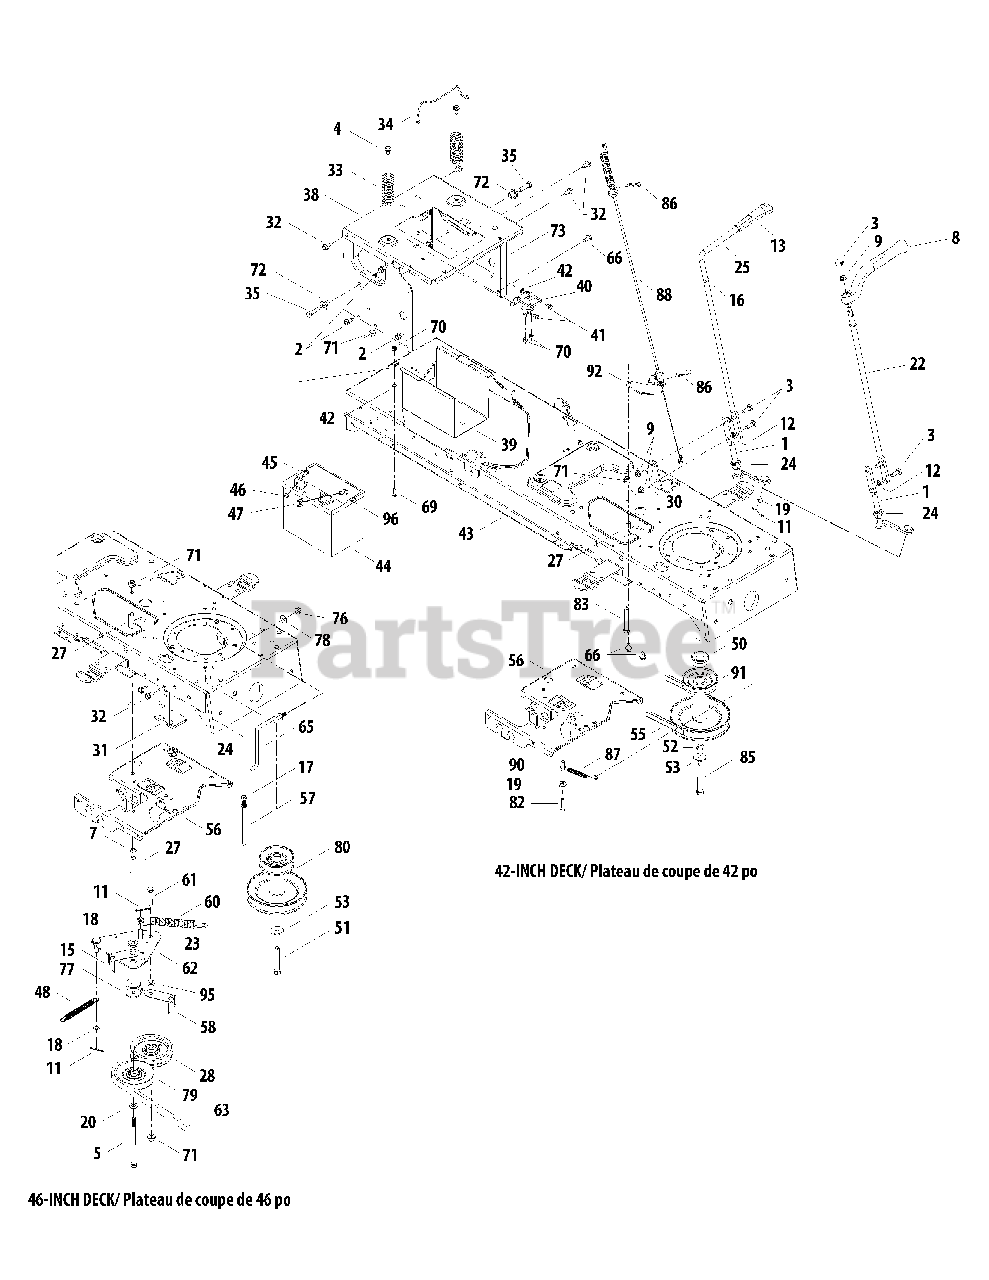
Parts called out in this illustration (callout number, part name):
1	PTO Engage Lever Assembly
2	Hex TT Scr. 5/16-18 x .75
3	Carriage Bolt 5/16-18 x 1.00" Lg
4	Hex Wash HD AB Tap Scr 5/16-12 x .75
5	Hex Cap Screw, 3/8-16 x 1.5
7	Push Nut Bolt Retainer
9	Hex Flange L-Nut 5/16-18
11	Cotter Pin 1/8" Dia x 1.00
12	Push Speed Nut
16	Flat Washer .510 ID x .75 OD x .033
17	L-Wash 5/16 ID
18	Flat Washer .385 ID x .62 OD x .06
19	Flat Washer .28 ID x .74 OD x .063
20	Flat Washer .385 ID x .87 OD x .06
21	Cap Plug .812 dia.
22	Deck Engagement Handle
23	Shoulder Spacer
24	Hex Slpit Flange Bearing .50 ID
25	Deck Engagement Handle
27	Spacer .385 ID x .635 OD x 1.54
28	Flat Idler Pulley 3.5 OD
30	Engagement Stop Bracket
31	Deck Stop
32	Hex Wash HD AB Tap Scr 5/16 x .75
33	Compression Spring 1.28 x 3.125
34	Battery Retainer Rod
35	Hex Bolt 3/8-16 x 1.25
38	Frame Seat Bracket
41	Hex Wash S-Tapp Scr 1/4-20 x .50
42	Ext. L-Washer 1/4 ID
43	Lower Frame Assembly
44	Battery 245 CCA (Dry)
45	Carriage Bolt 1/4-10 x .75
46	Sems Hex Nut 1/4-20
47	Wing Nut 1/4-20 Thd.
48	Extension Spring .50 x 5.0
50	Spacer 1.010 x 1.4 x .825
51	Hex Bolt 7/16-20 x 2.75 Gr. 5
52	Flat Washer .450 x 1.25 x .164
53	Lockwasher 7/16 ID
55	PTO Belt (w/42" deck)
56	Steering Support Bracket
57	Keeper Pin 5/16 x 4.75
58	Belt Guard
60	Extension Spring .75 x 6.75
61	Hex TT Sems Scr. 3/8-16 x 1.5
63	PTO Belt (w/46" Deck)
65	Belt Keeper Rod
66	Hex Wash HD S-Tapp Scr 5/16-18 x .50
68	L-Wash 1/4 ID
69	Thd Forming Scr. 1/4-20 x .75 Lg.
70	Hex L-Flanged Nut 1/4-20 Gr. F Nylon
71	Flange Lock-Nut 3/8-16 Gr. F Nylon
72	Shoulder Spacer .38 x 1.0 x .70
77	Flat Washer .39 ID x 1.5 OD x .135
78	Cupped Washer .345 ID x .88 OD x .060
79	4" Dia. V-Idler
80	Engine Pulley 3.39 x 6.12 Dia 46" Trans.
80	Engine Pulley 3.56 x 6.12 Dia 46" Hydro
82	Hex Bolt 1/4-20 x 1.5
83	Hex Cap Screw, 3/8-16 x 2.5
85	Hex Bolt 7/16-20 x 3.25 Gr. 5
86	Bow Tie Cotter Pin
87	Extension Spring .38 OD x 3.9 Lg.
88	Deck Engage Cable
90	Spacer .260 x .375 x 1.030 Lg.
91	Engine Pulley 3.39 x 6.12 dia 42" Trans
91	Engine Pulley 3.56 x 6.12 Dia 42" Hydro
95	Flat Washer .406 ID x .812 OD x .134
96	Shoulder Screw, 1/4-20
